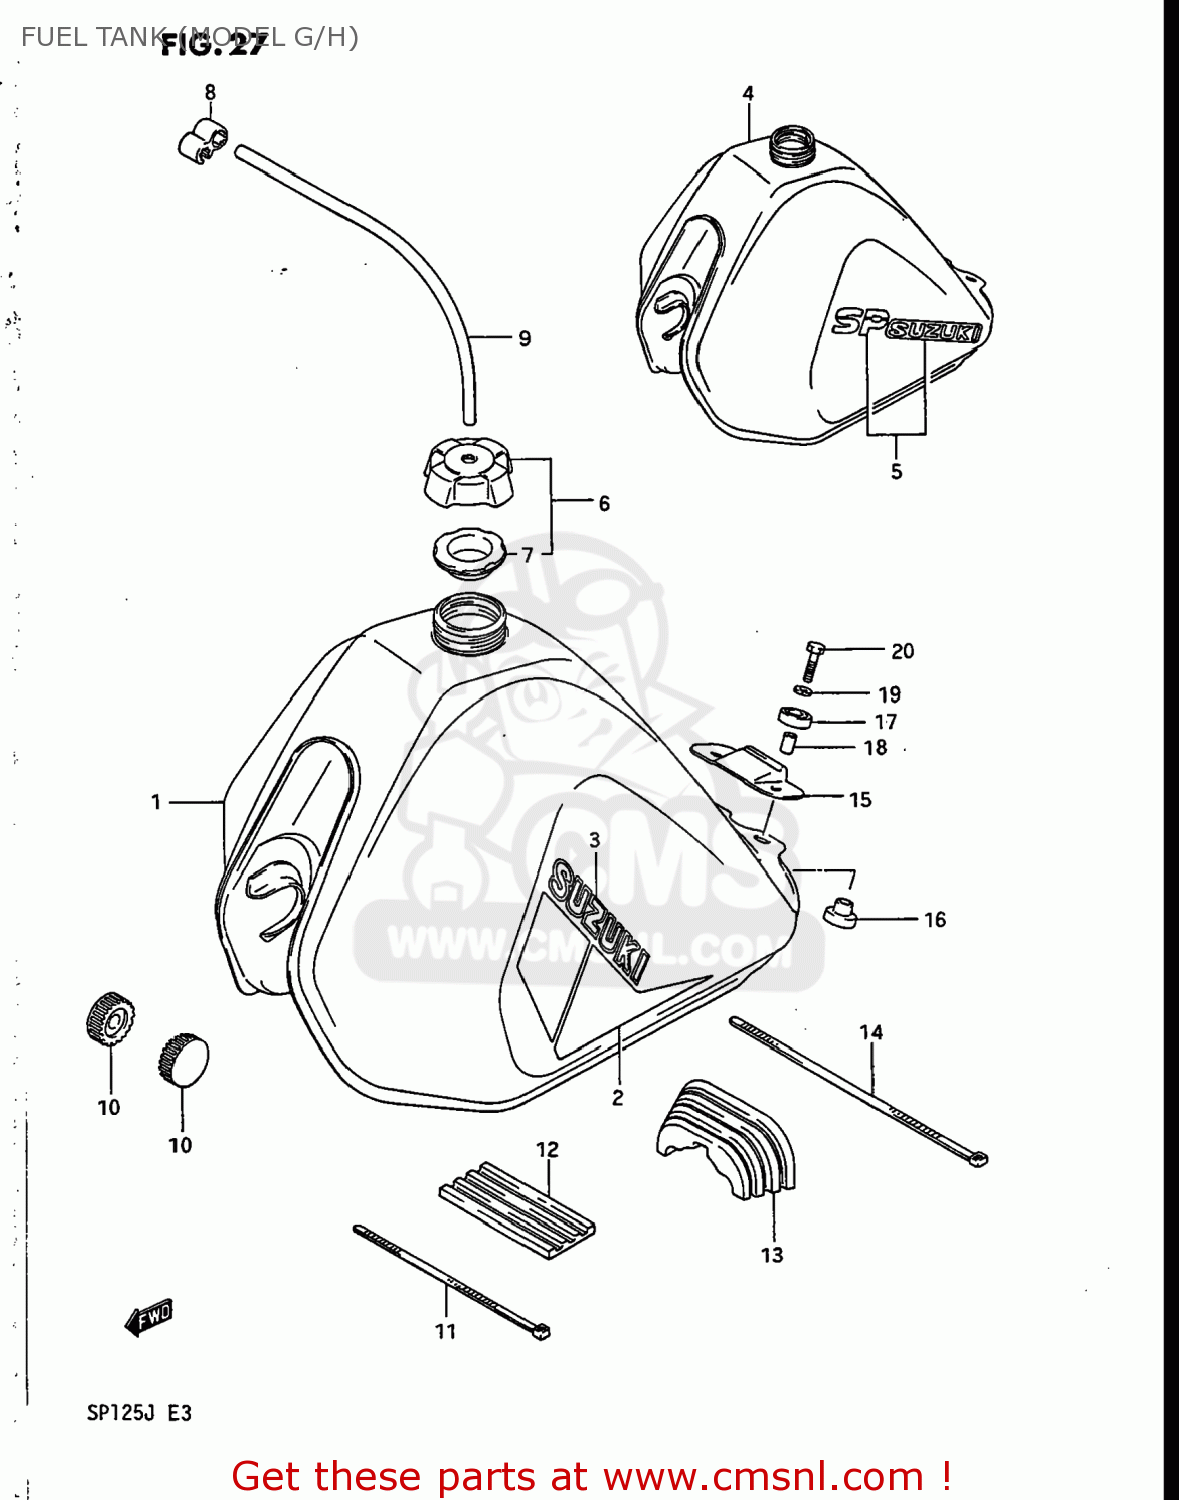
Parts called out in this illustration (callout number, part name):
1	TANK ASSEMBLY,FUEL
2	TAPE SET,FUEL TANK
3	EMBLEM(WHITE)
4	TANK ASSEMBLY,FUEL
5	TAPE SET,FUEL TANK
6	CAP SET,FUEL TANK
7	GASKET (NAS)
8	CLAMP,FUEL TANK BREATHER HOSE
9	HOSE
10	CUSHION
11	CLAMP
12	CUSHION,FUEL TANK UPR FR
13	CUSHION,FUEL TANK RR
14	CLAMP(L:250)
15	PLATE,SEAT FR HOOK
16	CUSHION
17	CUSHION
18	SPACER
19	WASHER,LOCK
20	BOLT
